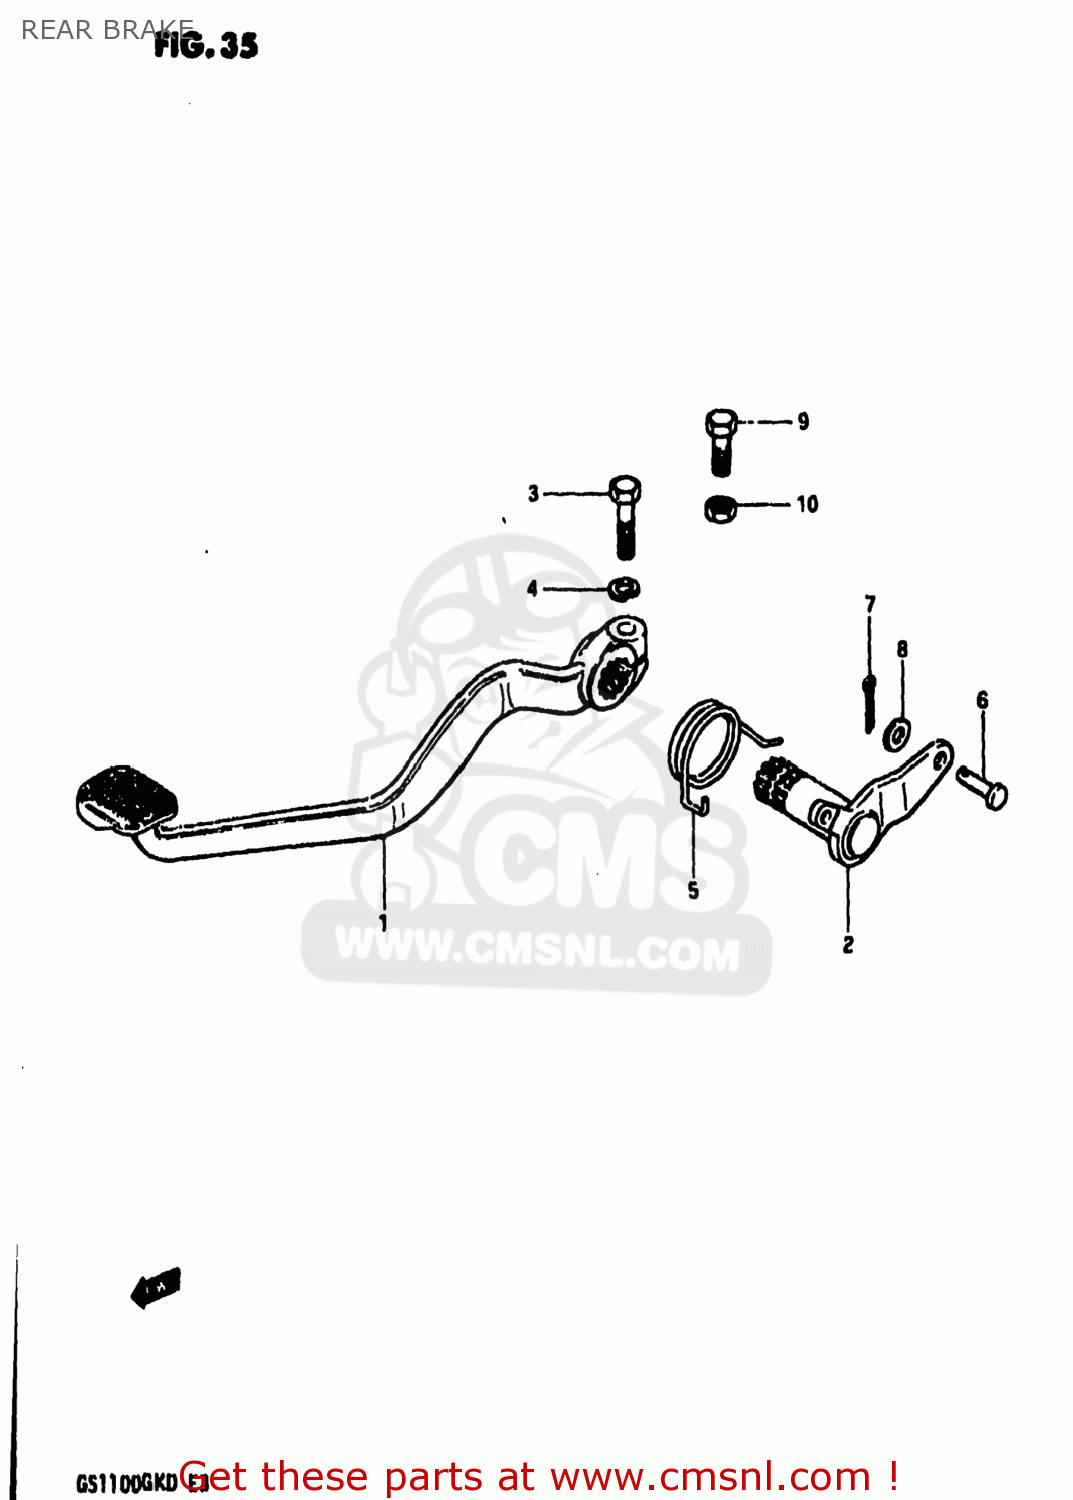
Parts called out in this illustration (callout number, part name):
1	PEDAL,BRAKE
2	ARM,BRAKE PEDAL ROD
3	BOLT
4	LOCK WASHER
5	SPRING
6	PIN
7	PIN
8	WASHER
9	BOLT
10	NUT
